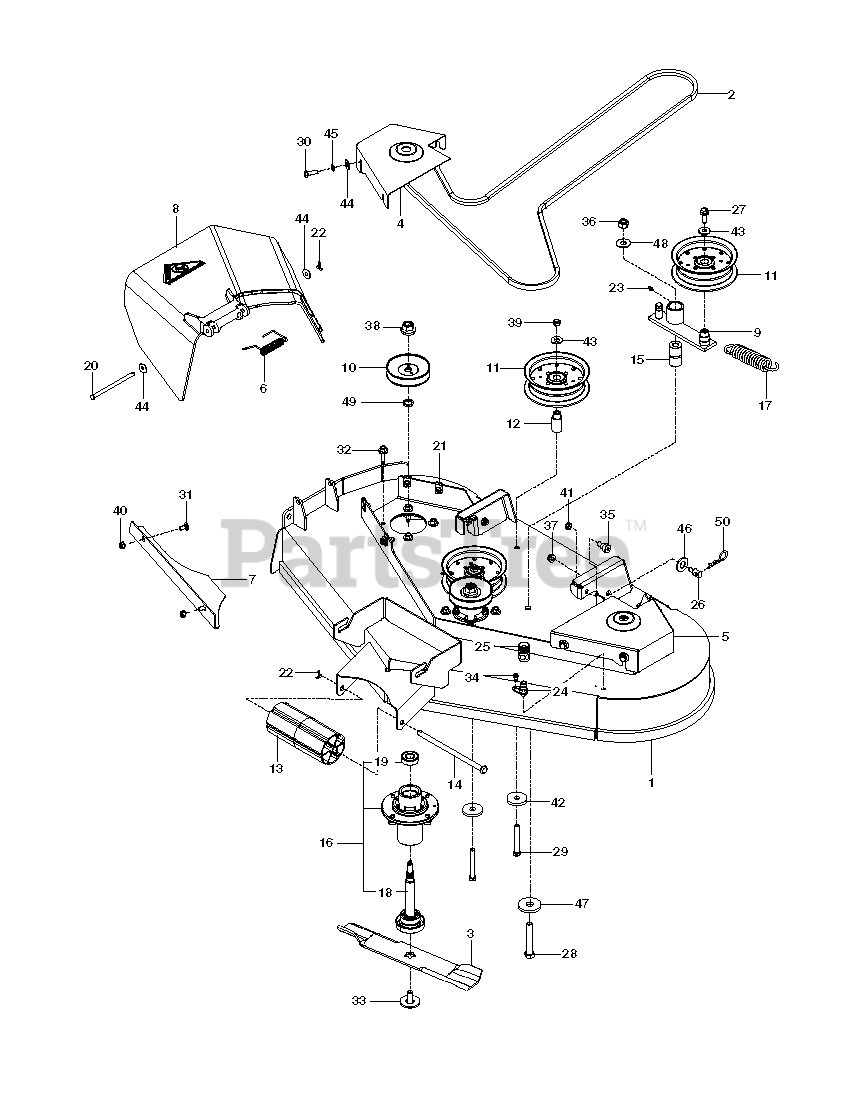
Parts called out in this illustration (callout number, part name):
1	DECK W/DECALS, 42 TF
3	BLADE, 14 5/8"
4	SHIELD, BELT RH - BLUE
5	SHIELD, BELT LH - BLUE
6	SPRING - TORSION
7	CONFINEMENT PLATE, 42"
8	DISCHARGE CHUTE 42"
9	IDLER ARM
10	PULLEY, MADREL 3.70 OP
11	PULLEY, IDLER
12	IDLER BUSHING
13	NOSE ROLLER 48"
14	ROD.ROLLER.NOSE.NARROW.48"
15	PIVOT BUSHING
16	MANDREL ASM, CAST IRON
18	SHAFT ASM MANDREL
19	BEARING
20	PIN-CLEVIS 5/16 DIA X 5.19 ZD
21	U-CLIP 5/16-18 NUT RETAINER
22	COTTER PIN 1/8 X 3/4
23	ZERK
24	PORT.WASHOUT
25	COUPLING.QUICK CONNECT
26	STUD.FASTNER.W/ANTI-ROTATE
27	HCS 3/8C X 1 SERRATED HEAD
28	HCS 1/2C X 3 1/4
29	HCS 3/8C X 3
30	HCS 5/16C X 1
31	CARRIAGE BOLT 5/16C X 5/8"
33	BOLT.WASHER.ASM.7/16-2
34	BOLT 1/4-20 X 1/2 HWST
35	SB 3/8-16 X 3/8 SKT HD ZD
36	NUT 1/2-13 HEX NYLOC ZD
37	5/16-18 NYLOC FLANGE NUT
39	NUT 3/8-16 NYLOC
40	NUT 5/16 NYLOC
41	NUT HEX 3/8-16 NYLON, THIN
42	SPINDLE WASHER
43	WASHER 3/8 FLAT
44	WASHER 5/16 FLAT
45	WASHER 5/16 LOCK
46	WASHER 5/8 FLAT
47	WASHER, SUPPORT
48	WASHER 1/2 FLAT
50	HAIRPIN #4
